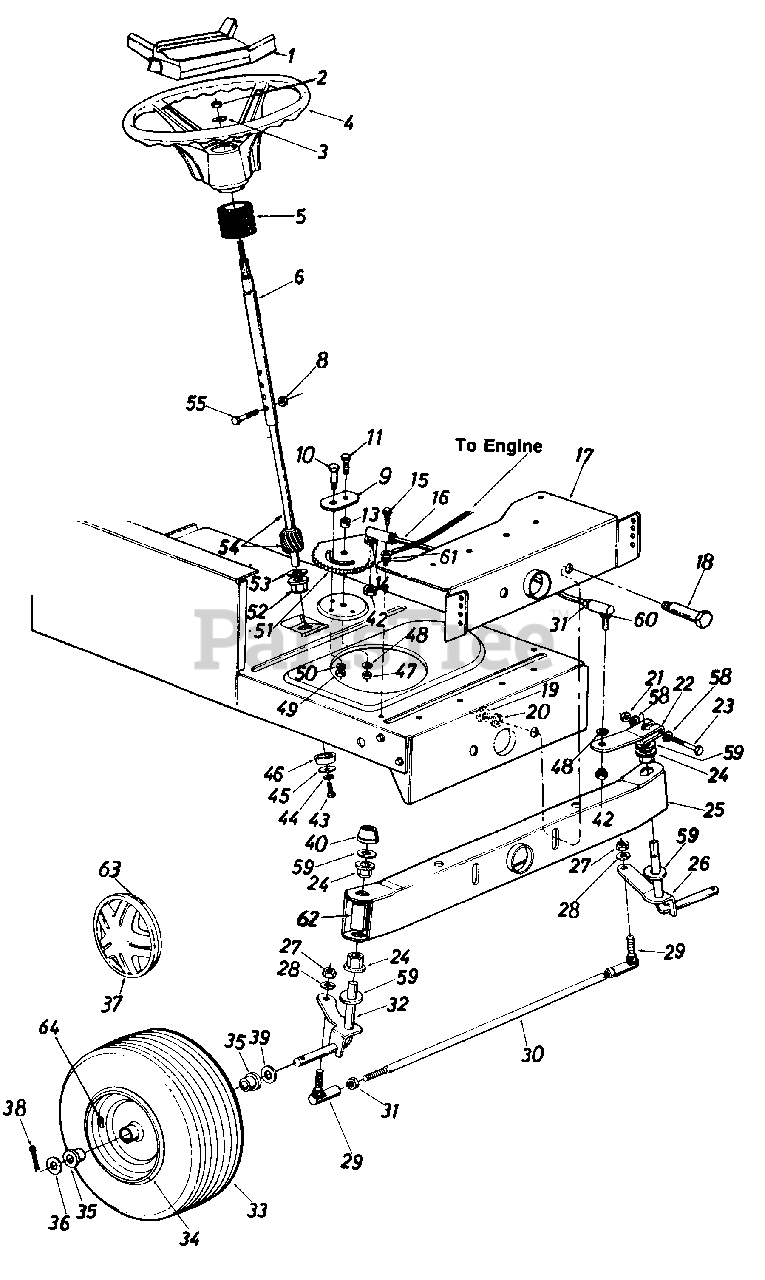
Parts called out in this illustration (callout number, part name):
1	Steering Wheel Insert
2	Hex L-Nut 5/16-24 Thd.
3	Belleville Wash. .345" I.D.
4	Steering Wheel
5	Steering Bellow
6	Steering Column Ass'y.
8	Hex L-Nut 1/4-20 Thd.
9	Retainer Plate
10	Shoulder Bolt .437" Dia. x .35 Lg. 5/16-18 Thd.
11	Hex Bolt 3/8-24 x 1.0" Lg. (Grade 5)
13	Spacer .380" I.D. x .625" O.D. x .227
14	L-Wash. 3/8" I.D.
15	Hex Wash. Hd. Self-Tap Scr.
16	Steering Drag Link
17	Front Pivot Brkt.
18	Shoulder Bolt .498" Dia. x 2.04 Lg. 3/8-16 Thd.
19	Hex Nut 3/8-16 Thd.
20	L-Wash. 3/8" I.D.
21	Hex Cent. L-Nut 5/16-24 Thd.
22	Steering Arm Front Axle
23	Hex Bolt 5/16-24 x 2.00" Lg. (Grade 5)
24	Hex Flg. Brg. .634 I.D.
26	Front Axle Ass'y. L.H.
27	Hex Nut 3/8-24 Thd.
28	L-Wash. 3/8" I.D.
29	Ball Joint 3/8-24 Thd.
30	Tie Rod
31	Hex Jam Nut 3/8-24 Thd.
32	Front Axle Ass'y. R.H.
33	Wheel Ass'y. Comp.
34	Front Wheel Rim Only
35	Bronze Flange Bearing
36	Fl-Wash. .635 I.D. x 1.59" O.D.
37	Front Wheel Hub Cap
38	Cotter Pin 1/8" Dia. x 1.25"
39	Fl-Wash. .640" I.D. x 1.24" O.D.
40	Push Cap 5/8" Dia. Rod
42	Hex Jam Nut 3/8-24 Thd.
43	Hex L-Bolt 5/16-18 x .62"
44	L-Wash. 5/16" I.D.
45	Fl-Wash. .33" I.D. x 1.25" O.D.
46	Spacer (Plastic)
47	Hex Nut 3/8-24 Thd.
48	L-Wash. 3/8" I.D.
49	Hex Nut 5/16-18 Thd.
50	L-Wash. 5/16" I.D.
51	Steering Gear Segment
52	Hex Flg. Brg. .634 I.D.
53	Fl-Wash. (Hardened)
54	Steering Shaft Lower
55	Hex Bolt l/4-20 x 1.25" Lg.
58	Wave-Wash. .32" I.D. x .62" O.D.
59	Fl-Wash. (Hardened)
60	Drag Link Ball Joint 3/8-24 Thd.
61	Ext. L-Wash. 5/16" I.D.
62	Plastic Tube
63	Spring Clip
64	Air Valve
